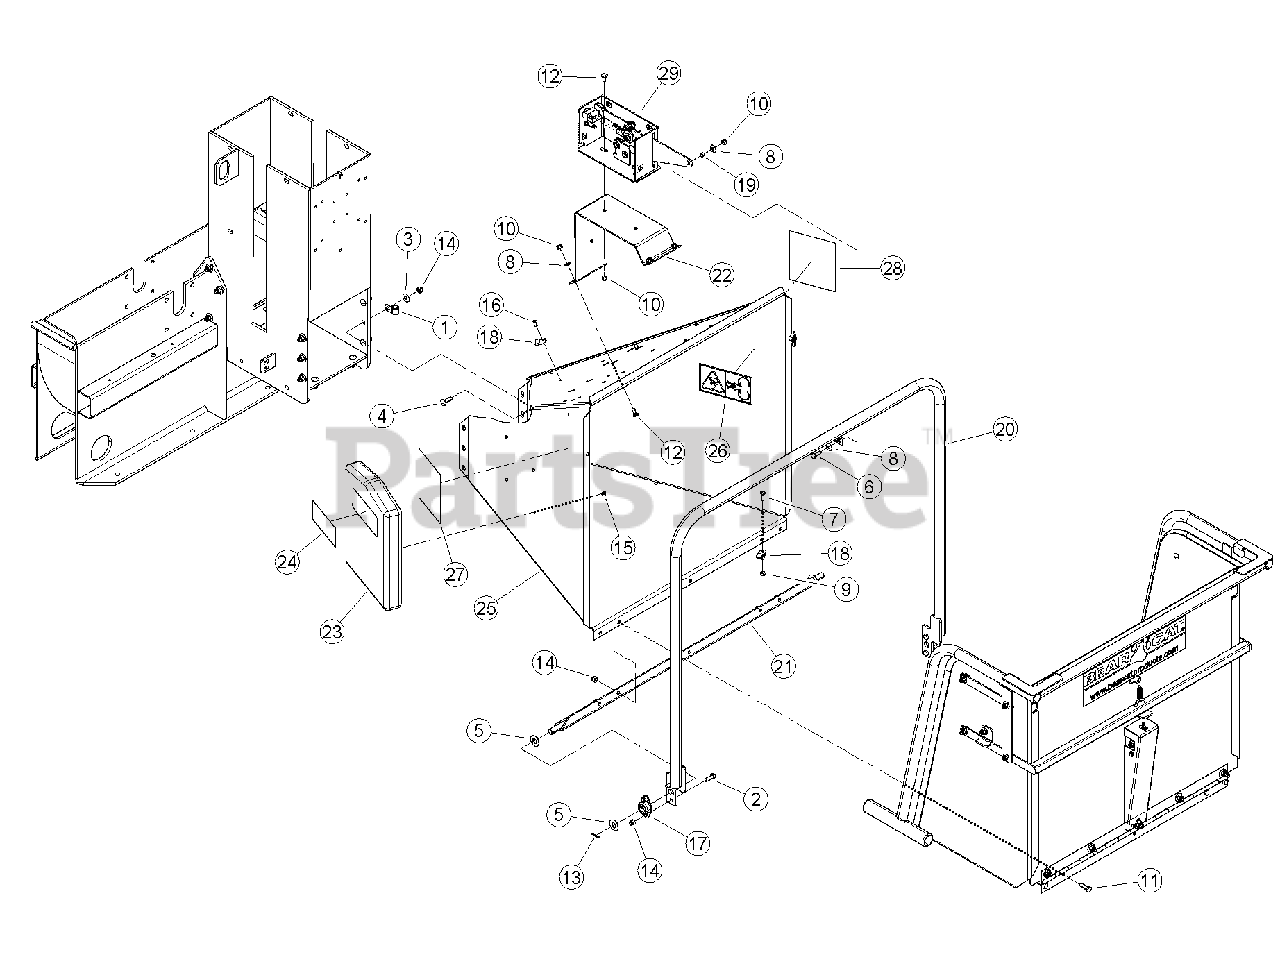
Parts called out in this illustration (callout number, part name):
1	CLAMP, 9/16 COATED
2	BOLT, 3/8 X 1 HEX HD GR5 ZP
3	WASHER, 3/8 FLAT ZP
4	BOLT, 3/8 X 1-1/2 CRG GR5 NC ZP
5	WASHER, 5/8 SAE FLAT ZP
6	BOLT, 5/16 X 1 HHCS GR5 NC ZP
7	BOLT, 1/4 X 1 CRG GR5 NC ZP
8	WASHER, 5/16 FLAT ZP
9	NUT, 1/4 NE NYLOCK ZP
10	NUT, 5/16 NE NYLOCK ZP
11	BOLT, 3/8 X 1-1/4 HEX HD GR5 ZP
12	BOLT, 5/16 X 3/4 CRG GR5 NC ZP
13	PIN, 1/8 X 1.00 ZP COTTER
14	NUT, 3/8 NE NYLOCK ZP
15	RIVET, AL BLIND 1/4 X 1/2 DOME HEAD
16	RIVET, AL BLIND 1/4 X 3/4 DOME HEAD
17	BEARING, SIDE FLANGE MOUNT, 5/8
18	CLAMP, CABLE MOUNT
19	SPACER, IDLER PIVOT
20	WELDMENT, CONTROL ARM
21	WELDMENT, CONTROL PIVOT
22	MOUNT, SWITCH BOX
23	ASSEMBLY, MANUAL CONTAINER SERVICE PART
24	DECAL, MUTILINGUAL MANUAL
25	ASSEMBLY, BIG CHIPPER CHUTE SERVICE PART
26	DECAL, BLADE DANGER ISO
27	DECAL, FEED POSITION
28	DECAL, FEED POSITION
29	ASSEMBLY, SWITCH BOX
